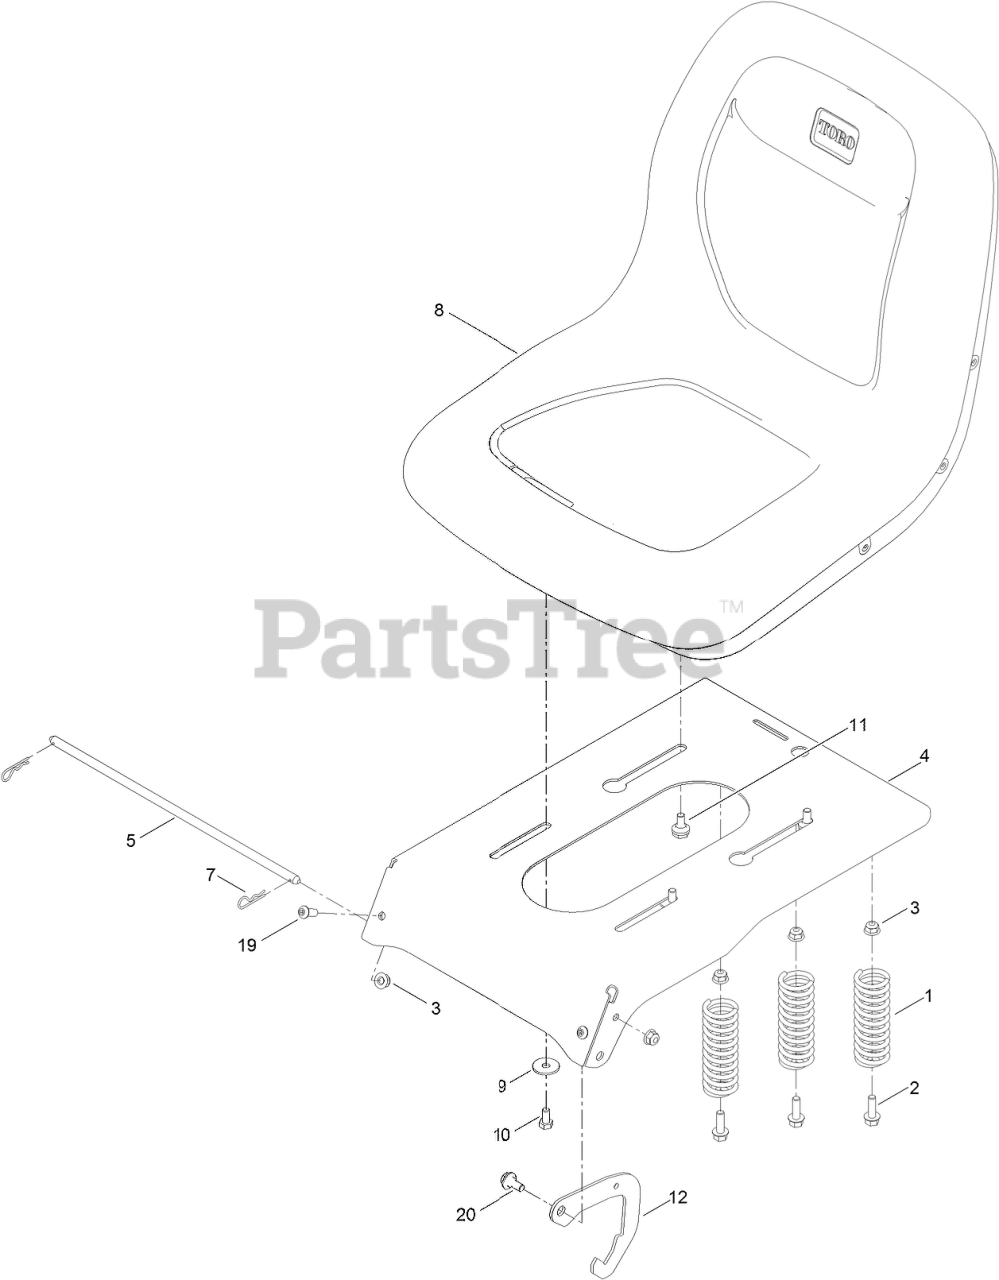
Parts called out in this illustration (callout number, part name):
1	SPRING-COMPRESSION
2	SCREW-HHF
3	NUT-HF, NI
4	PAN-SEAT
5	ROD-PIVOT, NARROW
7	PIN-COTTER
8	SEAT-18 INCH
9	WASHER-PIVOT
10	SCREW-HH
11	BOLT-SHOULDER,HFH
12	SEAT LATCH
19	SCREW-HSBH
20	SCREW-SHOULDER
